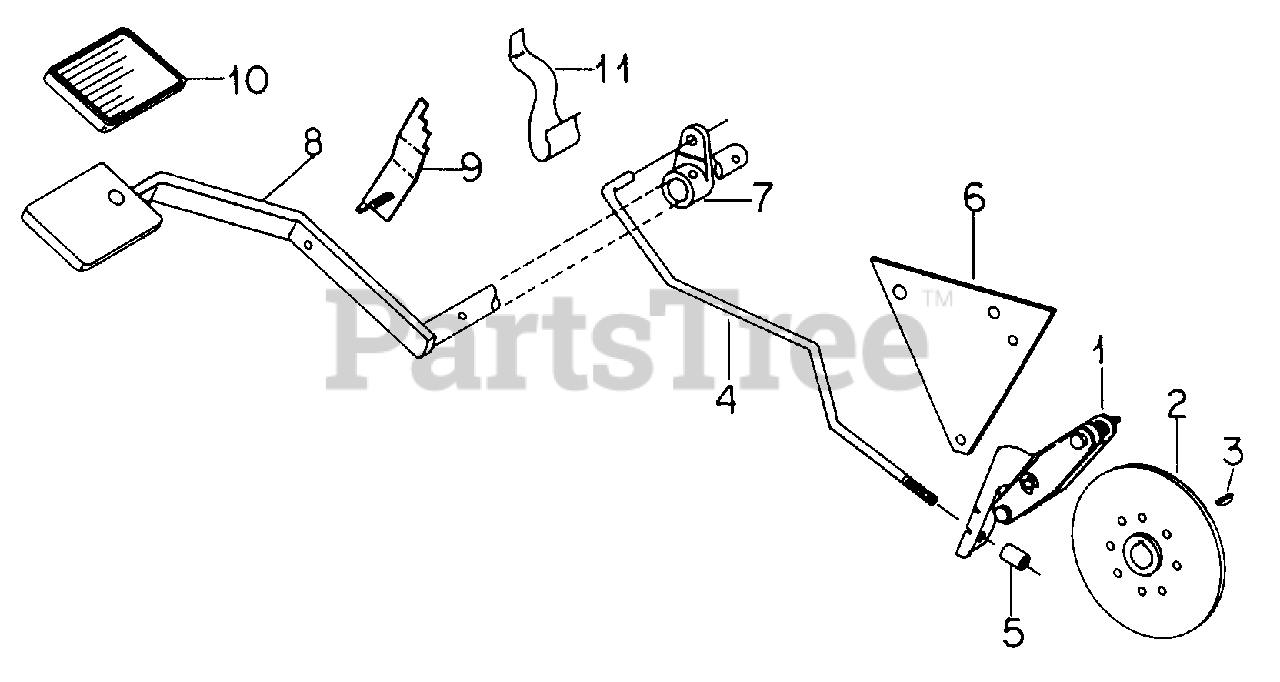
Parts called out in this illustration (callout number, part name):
1	Brake Assy, Caliper
2	Disk & Hub
3	Key, 3/16 X 3/4 Woodruff
4	Rod, Brake
5	Spacer, .493 X .675 X 1.00 Pipe
6	Support, Plate Brake, Spacer
9	Ratchet
10	Pad, Pedal
11	Spring, Switch Operating
